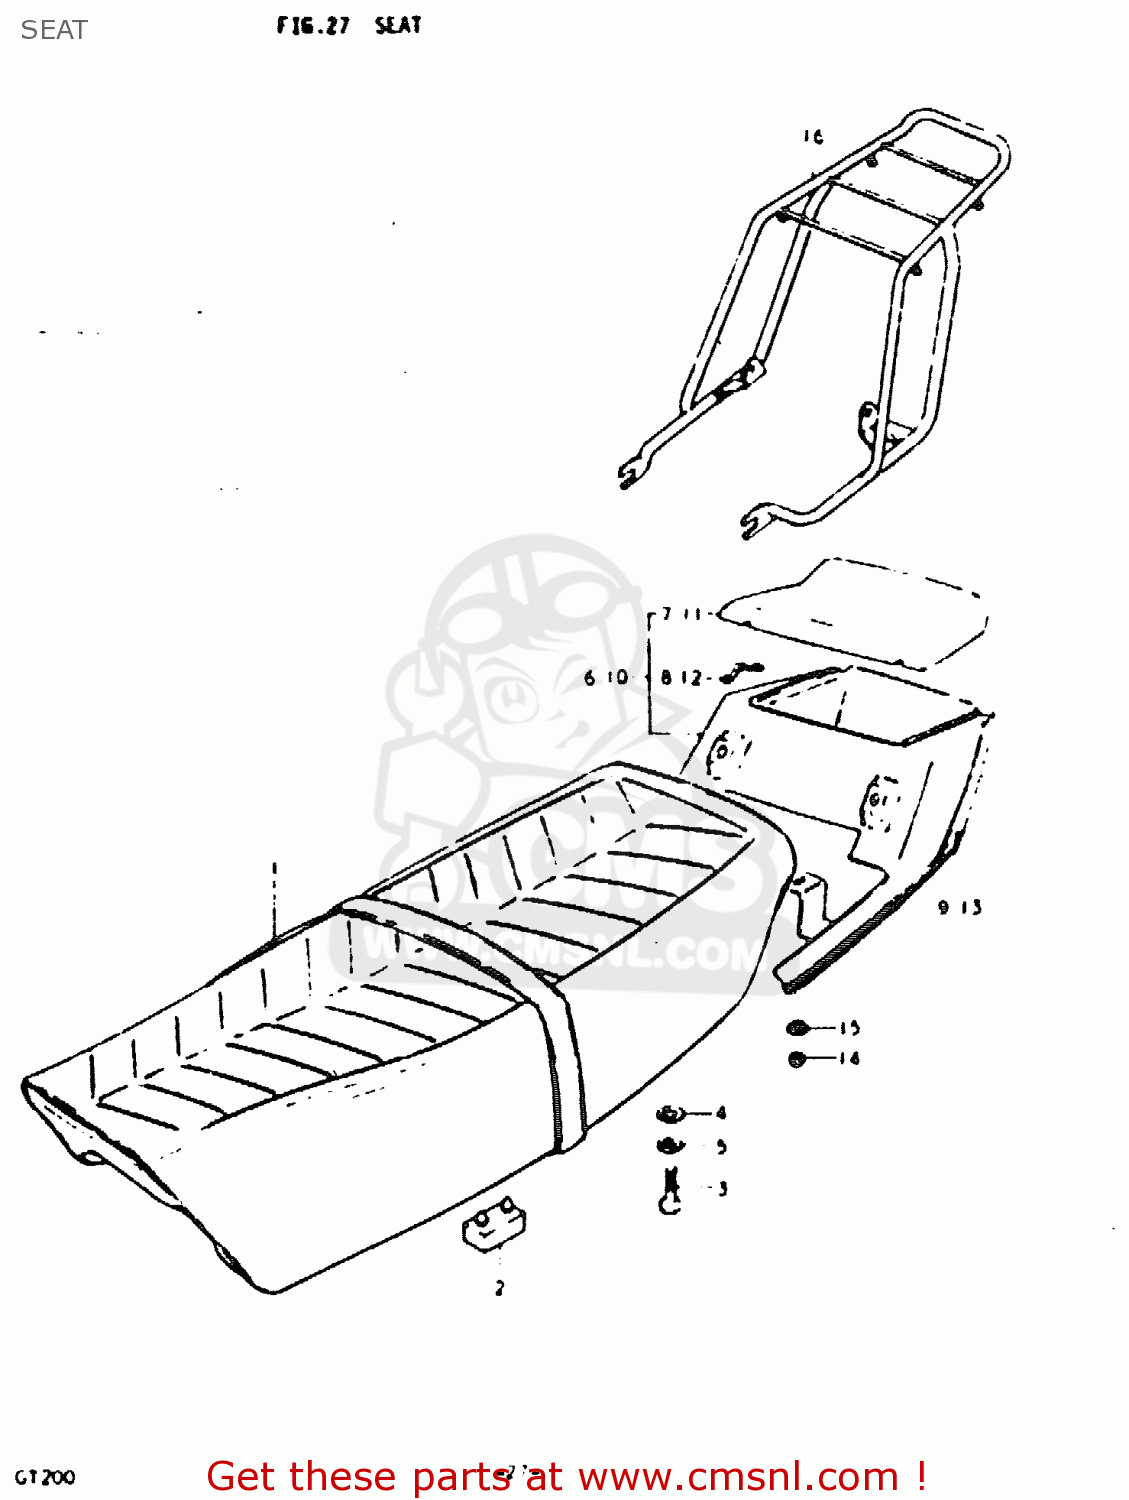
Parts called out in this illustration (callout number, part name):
1	SEAT
2	CUSHION
3	BOLT
4	WASHER (8.2X20X1.6)
5	LOCK WASHER
6	TAIL COVER, SEAT
7	LID, TALE COVER
8	SPRING
9	TAPE SET, STRIPING
10	TAPE COVER, SEAT
11	LID, TAPE COVER
12	SPRING
13	TAPE SET, STRIPING
14	NUT 6MM
15	WASHER
16	CARRIER, SPORTS
